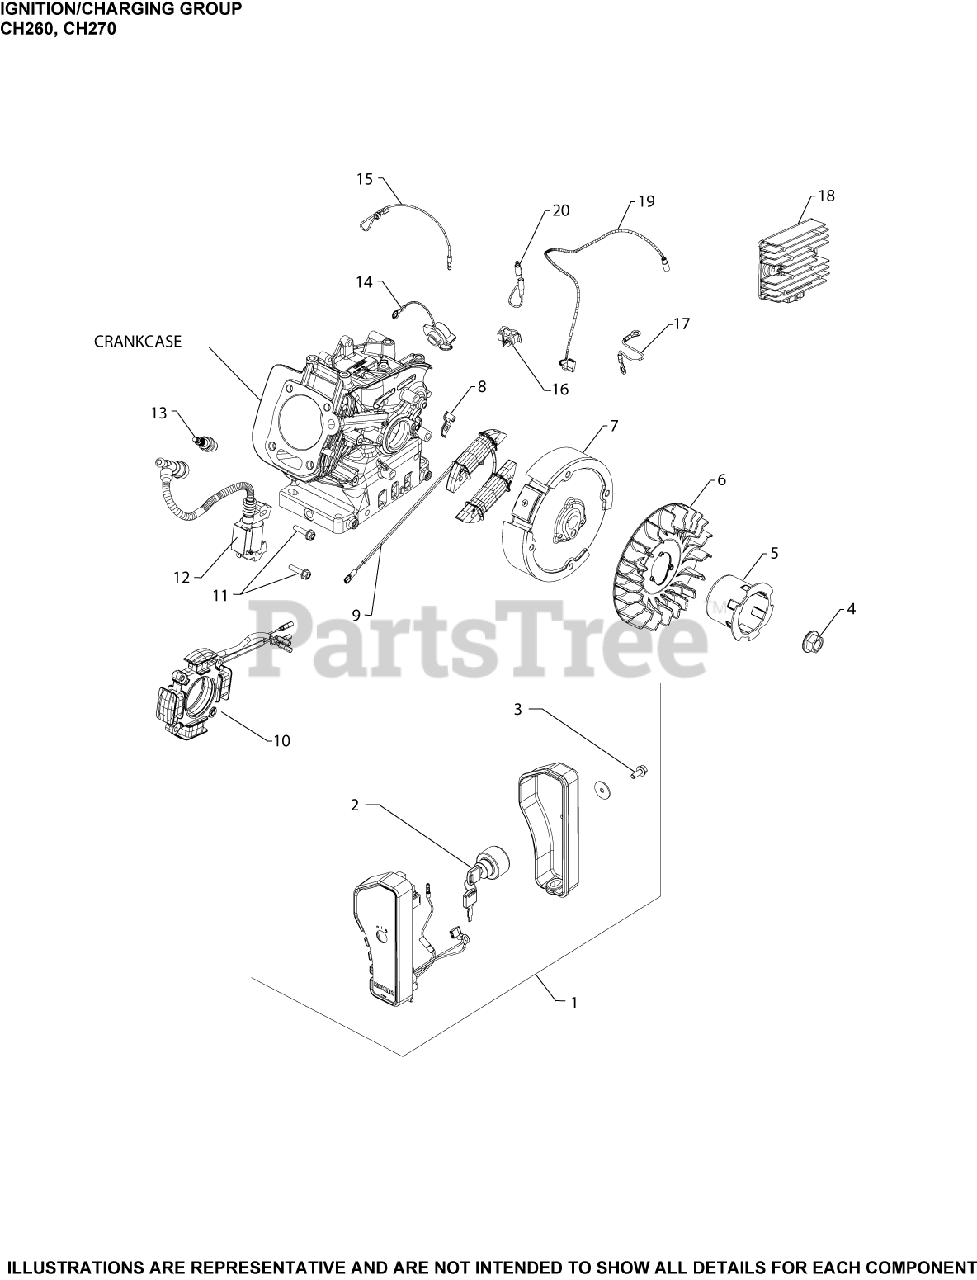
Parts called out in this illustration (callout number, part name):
4	NUT, FLYWHEEL
5	CUP, STARTER DRIVE
6	FAN, FLYWHEEL
7	FLYWHEEL ASSEMBLY, CAST IRON USE 17 025 28-S
11	SCREW, M6 X 25 USE 25 086 436-S
12	MODULE, IGNITION
13	SPARK PLUG, RFI
14	SWITCH, IGNITION
16	CLIP, WIRE HARNESS
20	LEAD, OPTIONAL EQUIPMENT
